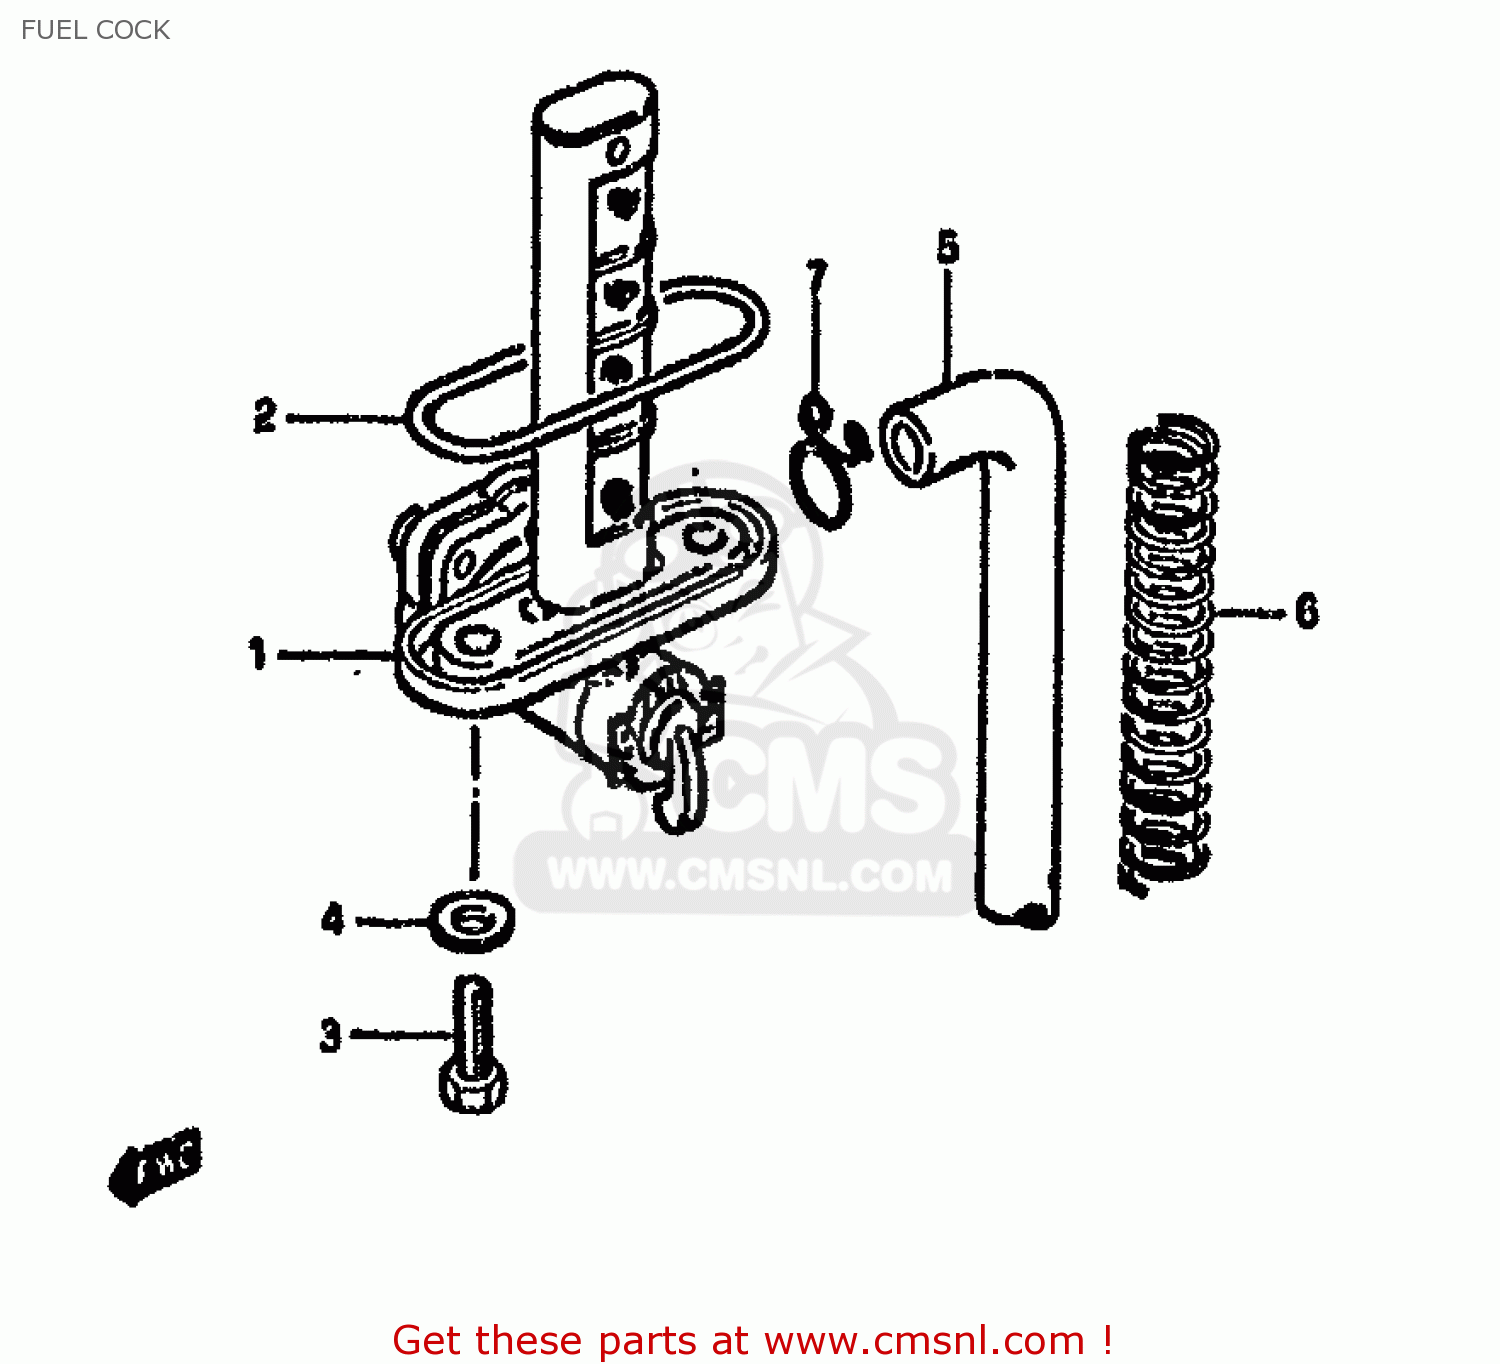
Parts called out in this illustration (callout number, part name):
1	COCK ASSEMBLY,FUEL
2	O RING
3	BOLT(6X20)
4	GASKET
5	HOSE
6	SPRING
7	CLIP
